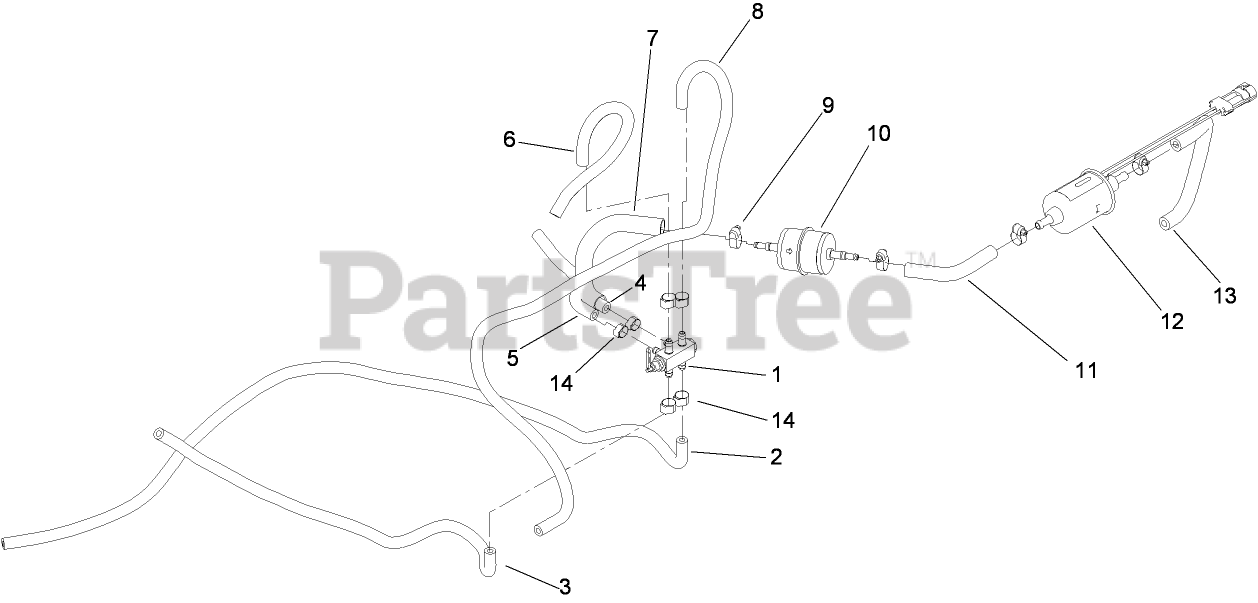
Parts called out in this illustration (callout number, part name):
1	VALVE-FUEL, DUAL FLOW
2	HOSE-FUEL
3	HOSE-FUEL
4	HOSE-FUEL
5	HOSE-FUEL
6	HOSE-FUEL
7	CONDUIT-FUEL LINE
8	HOSE-FUEL
9	CLAMP-WORM
10	FILTER-INLINE
11	HOSE-FUEL
12	PUMP-FUEL
13	HOSE-FUEL
14	CLAMP-HOSE, FUEL
